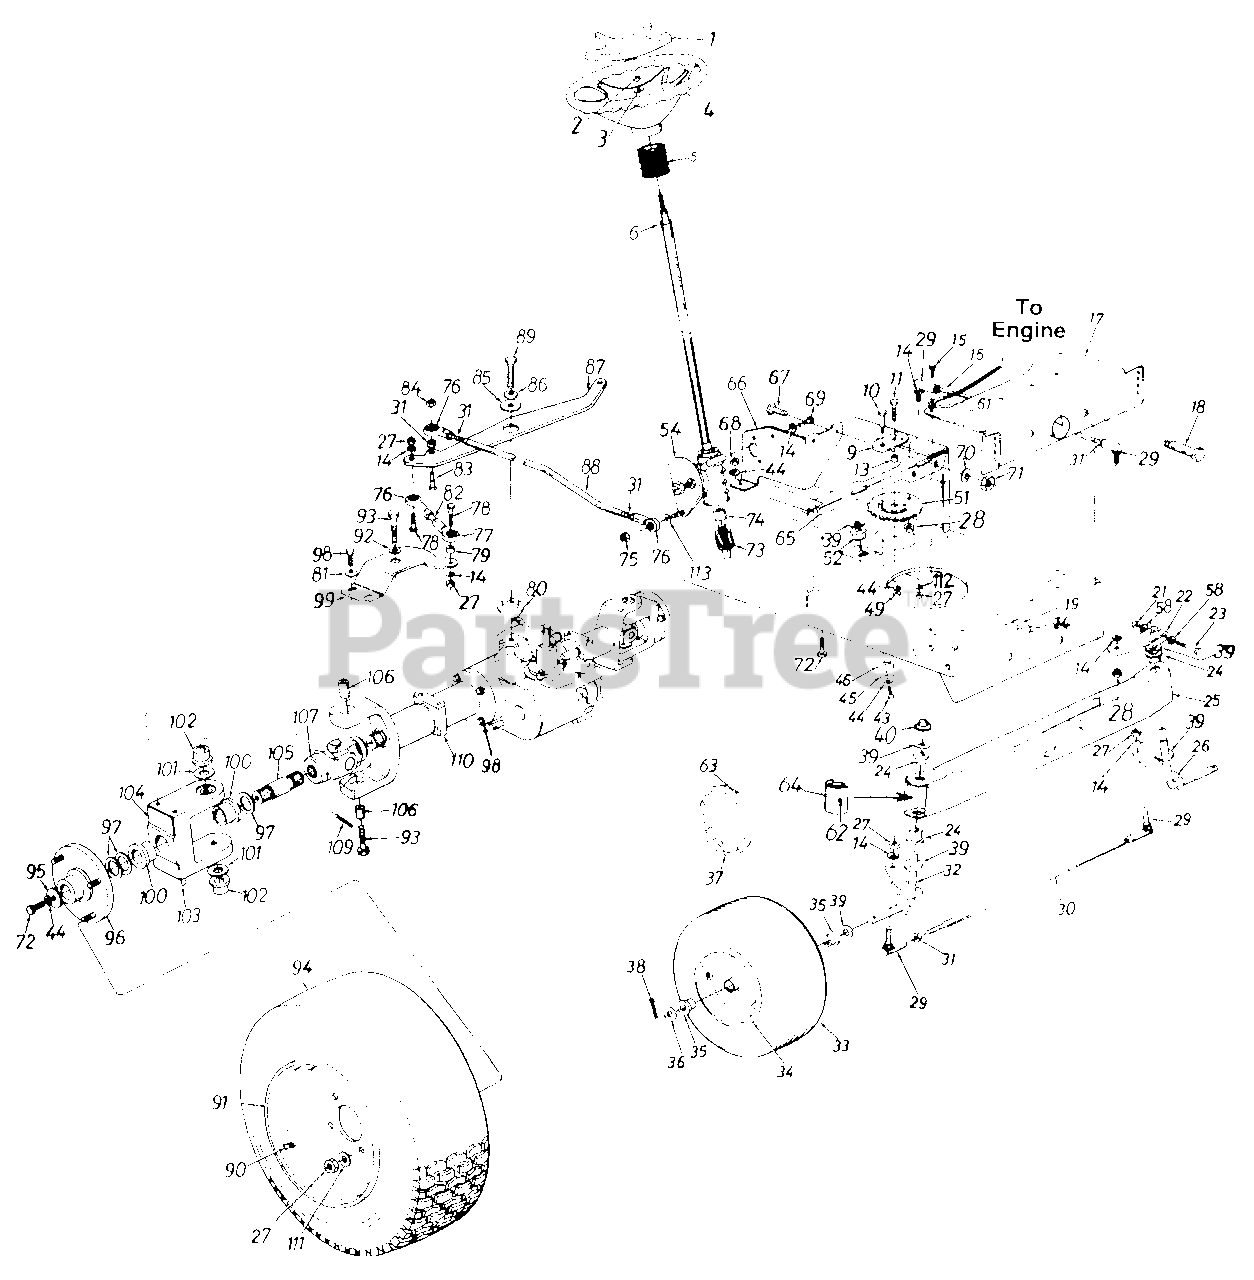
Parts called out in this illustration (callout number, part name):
1	Steering Wheel Cap
2	Hex L-Nut 5/16-24 Thd.
3	Belleville Wash. .345" I.D.
4	Steering Wheel
5	Steering Bellow
6	Steering Shaft Ass'y.
9	Retainer Plate
10	Shoulder Bolt .437" Dia. x .35" Lg. 5/16-18 Thd.
11	Hex Bolt 3/8-24 x 1.0" Lg. (Grade 5)
13	Spacer.380" I.D. x .625" O.D. x .227"
14	L-Wash. 3/8" I.D.
15	Hex Wash. Hd. Self-Tap Scr.
16	Steering Drag Link
17	Front Pivot Brkt.
18	Shoulder Bolt .498" Dia. x 2.04" Lg. 3/8-16 Thd.
19	Hex Nut 3/8-16 Thd.
21	Hex Cent. L-Nut 5/16-24 Thd.
22	Steering Arm Front Axle
23	Hex Bolt 5/16-24 x 2.00" Lg. (Grade 5)
24	Hex Flg. Brg. .634" I.D.
26	Front Axle Ass'y. - L.H.
27	Hex Nut 3/8-24 Thd.
28	Hex Jam Nut 3/8-24 Thd.
29	Ball Joint 3/8-24 Thd.
31	Hex Jam Nut 3/8-24 Thd.
32	Front Axle Ass'y. - R.H.
35	Ball Bearing
36	Fl-Wash. .635" I.D. x 1.59" O.D.
37	Front Hub Cap
38	Cotter Pin 1/8" Dia. x 1.25" Lg.
39	Fl-Wash. .640" I.D. x .24" O.D.
43	Hex L-Bolt 5/16-18 x .62"
44	L-Wash. 5/16" I.D.
45	Fl-Wash. .33" I.D. x 1.25" O.D.
46	Spacer (Plastic)
49	Hex L-Nut 5/16-18 Thd.
51	Steering Gear Segment
52	Hex Flg. Brg. .634 I.D.
54	Steering Ass'y. Comp.
58	Wave Wash. .32" I.D. x .62"
61	Ext. L-Wash. 5/16" I.D.
62	Grease Fitting
63	Spring Clip
64	Pivot Bar End Cap
65	Horizontal Cross Bracket
66	Vertical Mounting Bracket
67	Hex Bolt 1/4-28 x .75" Lg.
68	Hex Nut 5/16-24 Thd.
69	Hex Bolt 3/8-16 x 1.0" Lg.
70	Bell-Wash. .265" I.D. x .75"
71	Hex Nut 1/4-28 Thd.
72	Hex Bolt 5/16-24 x .75" Lg.
73	Pinion Shaft
74	Steering Shaft Splined Coupler
75	Hex L-Nut 3/8-24 Thd.
76	Rod End 3/8-24 Thd. - R.H.
77	Rod End 3/8-24 Thd. - L.H.
78	Hex Bolt 3/8-24 x 1.5" Lg. (Gr. 5)
79	Spacer .38" I.D. x .625"
80	Shld. Spacer .51" I.D.
81	Bell-Wash. .38" I.D. x .88"
83	Hex Bolt 3/8-24 x 1.25" Lg.
84	Hex Patch L-Nut 3/8-24 Thd.
85	Fl-Wash. .531" I.D. x 1.75"
86	Bell-Wash. .505" I.D. x 1.0"
89	Hex Bolt 1/2-13 x 1.5" Lg. (Gr. 5)
90	Air Valve
93	Hex Bolt 1/2-20 x 1.75" Lg. (Gr. 5)
95	Fl-Wash. .33" I.D. x 1.25"
96	Wheel Flange Ass'y.
97	Fl-Wash. 1.0" x 1.56"
98	Hex Bolt 3/8-24 x 1.25" Lg.
101	Fl-Wash. .76" I.D. x 1.5"
102	Flange Brg. 3/4" I.D.
103	Grease Fitting
104	Wheel Brg. Housing
106	Pivot Sleeve
109	Grooved Roll Pin 1.0" Lg.
110	Axle Horn Ass'y.
111	Bell-Wash. .38" I.D. x .88"
112	Bell-Wash. .39" I.D. x 1.38"
113	Fl-Wash. .385" I.D. x .62"
